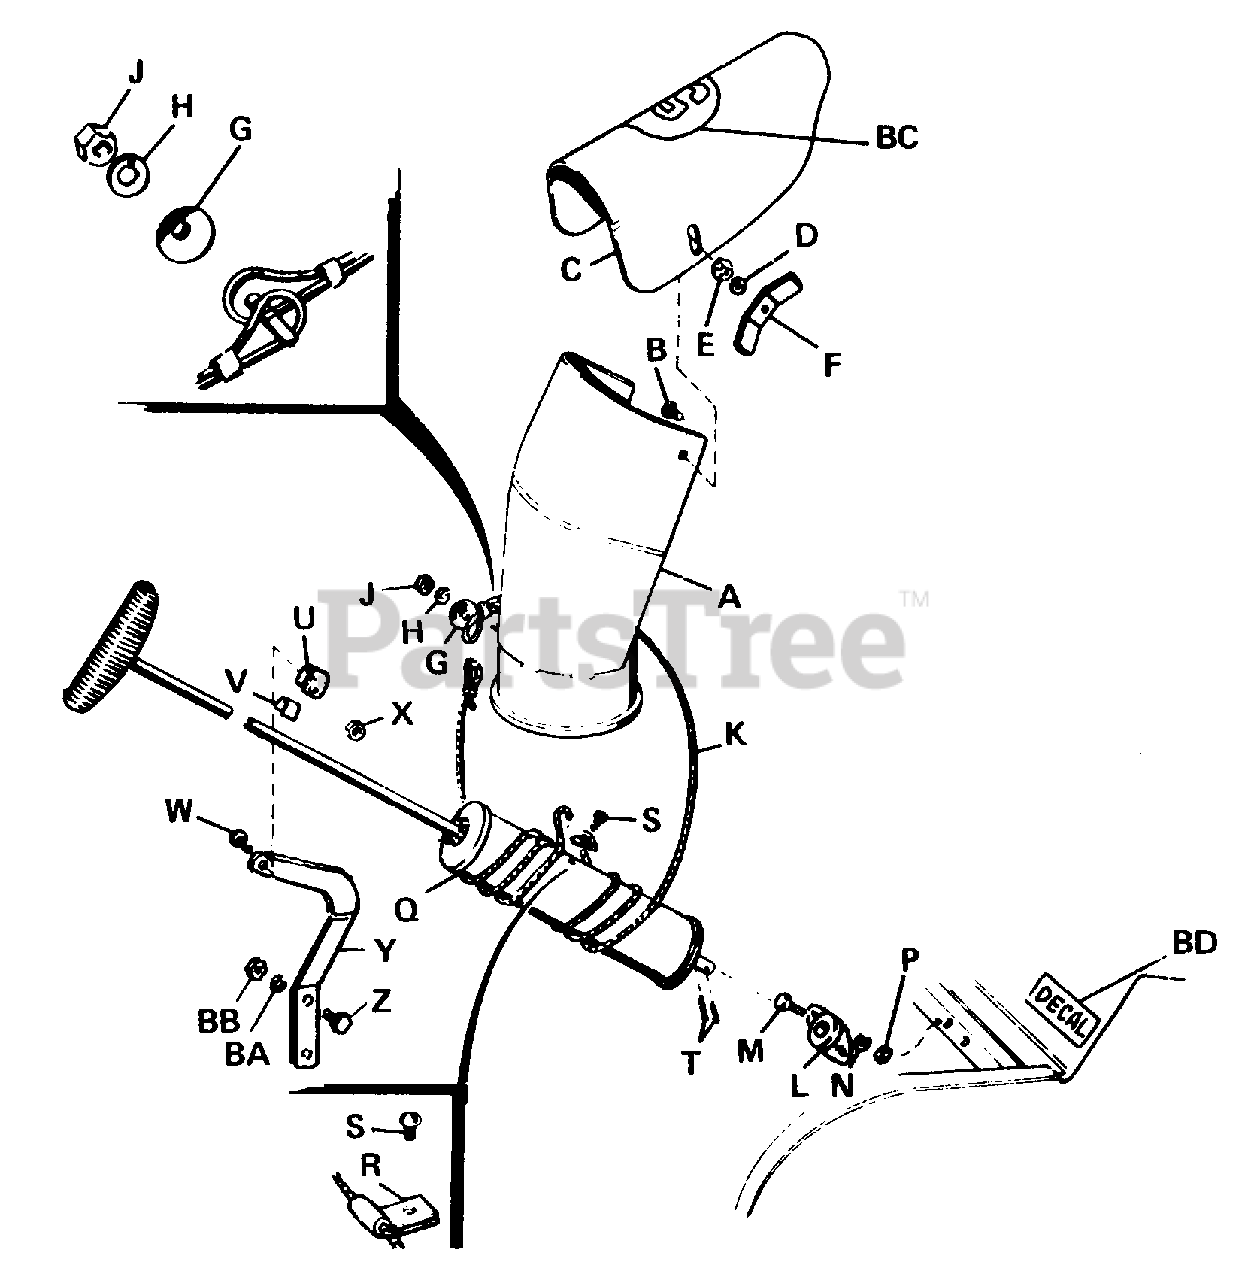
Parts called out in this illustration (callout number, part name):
A	Spout Assembly
B	Carriage Bolt, 5/16"-18 x 3/4"
C	Spout Extension
D	Washer, Plain 3/8"
E	Washer, Lock 3/8"
F	NUT, Wing, 5/16-18
G	Cup Washer
H	Washer, Lock 5/16"
J	Nut, Hex. Full, 5/16"-18
K	Cable Assembly
M	Capscrew, Hex., 1/4"-20 x 5/8"
N	Washer, Lock, 1/4"
P	Full Hex. Nut, 1/4"-20
Q	Tube Assembly, Spout Control
S	Self-Tapping Screw, 1/4"-20 x 3/8"
T	Cotter Pin, 1/8" x 3/4"
V	Liner, Guide
W	Capscrew, Hex., 5/16"-18 x 1/2"
X	Nut, Hex., Full, Lock, 5/16"-1
Y	Rod Guide Support
Z	Hex. Capscrew, 3/8"-16 x 1" lg.
BA	Lock Washer, 3/8"
BB	Hex. Nut, Full, 3/8"-16
